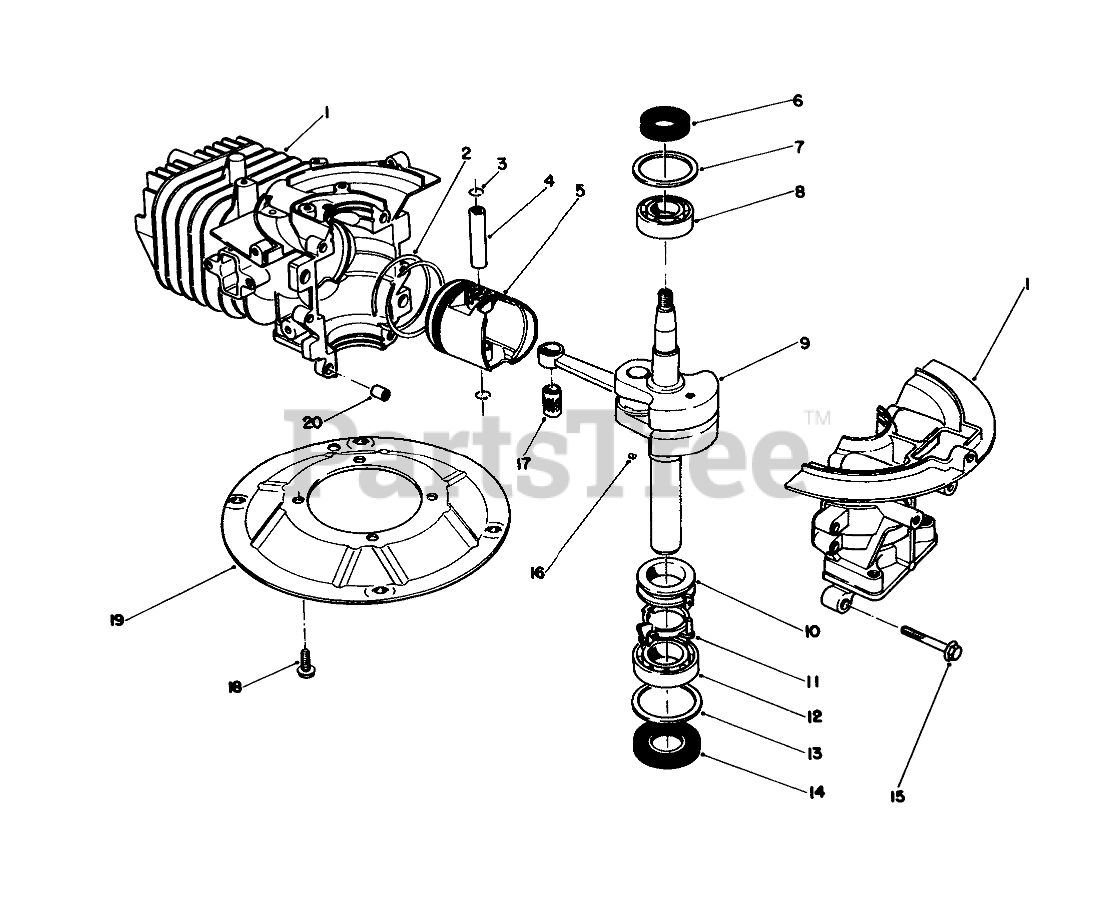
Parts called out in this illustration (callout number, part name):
1	CRANKCASE
2	CYLINDER/CRANKCASE
3	FLYWHEEL
4	Pin-Wrist
5	Piston (58 mm)
6	Oil Seal-Upper
7	GASKET
8	ASM - CARBURETOR
9	Pin-Wrist
10	SPACER
11	BRACKET
12	LOWER BRG
13	WASHER-LOWER
14	SEAL-OIL
17	BEARING
19	Plate-Mounting
